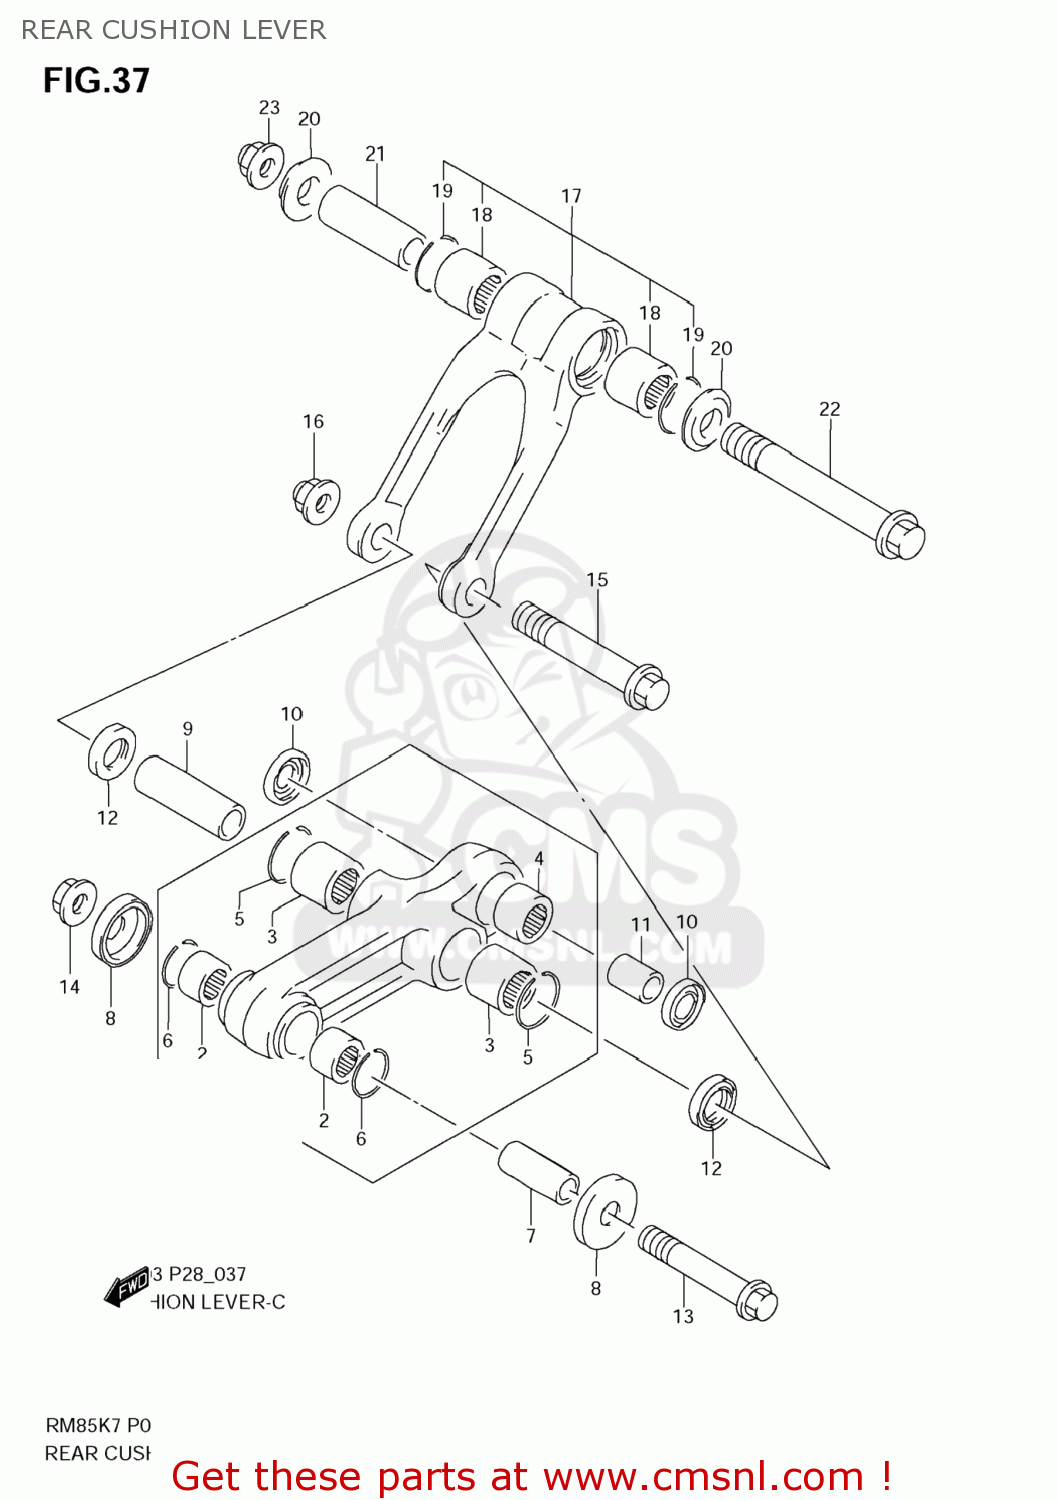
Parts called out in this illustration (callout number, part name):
1	LEVER SET,RR CUSHION
2	BEARING(14X20X12)
3	BEARING(17X24X20)
4	BEARING(20X26X12)
5	RING,STOPPER
6	CIRCLIP,PISTON PIN
7	SPACER,RR CUSHION LEVER FR
8	SEAL,RR CUSHION LEVER FR DUST
9	SPACER,RR CUSHION LEVER CTR
10	SEAL,OIL(20X26X4.5)
11	SPACER,RR CUSHION LEVER RR
12	SEAL,OIL(17X24X3)
13	BOLT,RR CUSHION LEVER FR
14	NUT
15	BOLT,RR CUSHION LEVER CTR
16	NUT
17	ROD SET,RR CUSHION LEVER
18	BEARING(17X24X20)
19	RING,STOPPER
20	SPACER,RR CUSHION ROD SIDE
21	SPACER,RR CUSHION ROD
22	BOLT,RR CUSHION ROD
23	NUT
